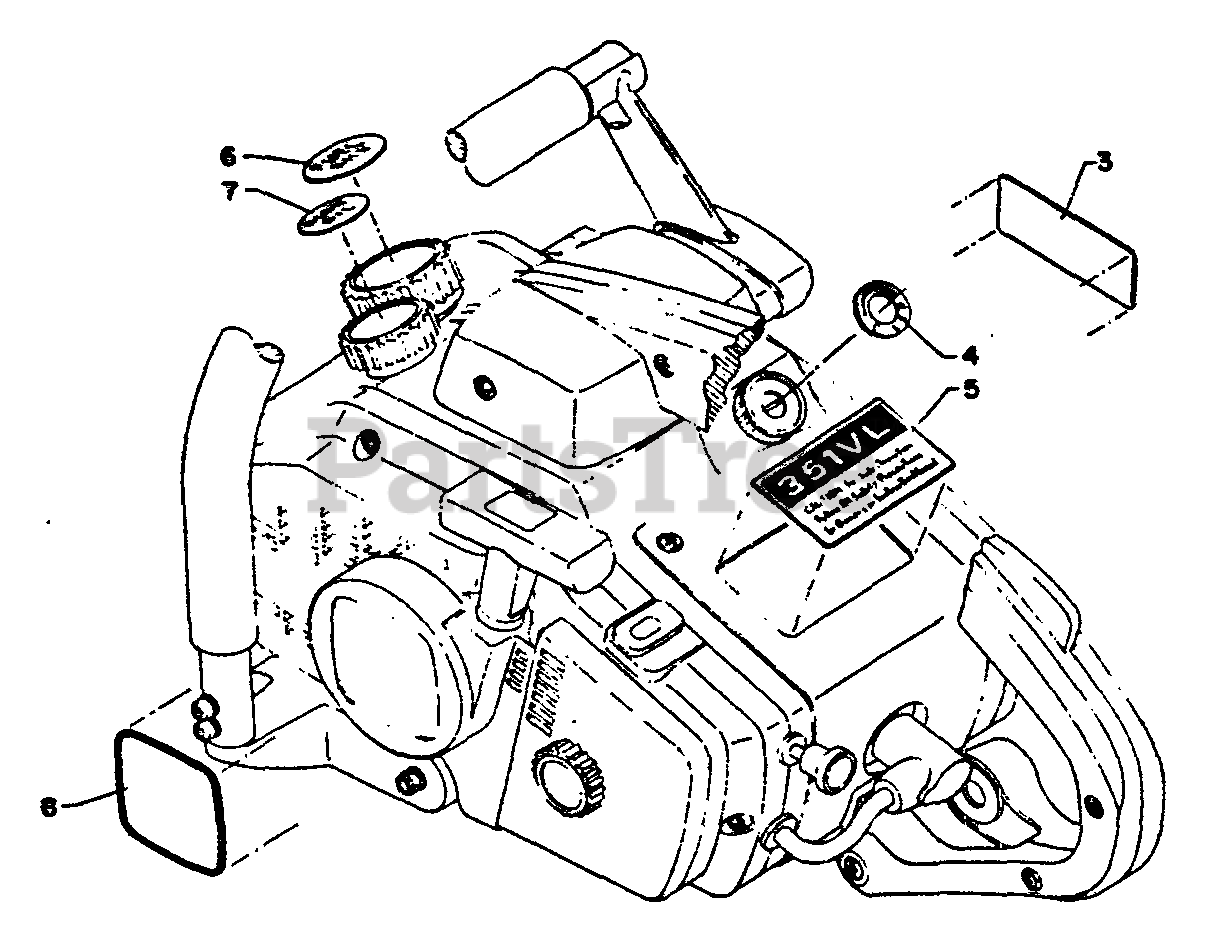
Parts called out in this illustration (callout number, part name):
3	LABEL - ECHO
4	LABEL - CAUTION
5	PLATE, MODEL
6	LABEL - FUEL
7	LABEL - OIL
8	LABEL - ECHO
